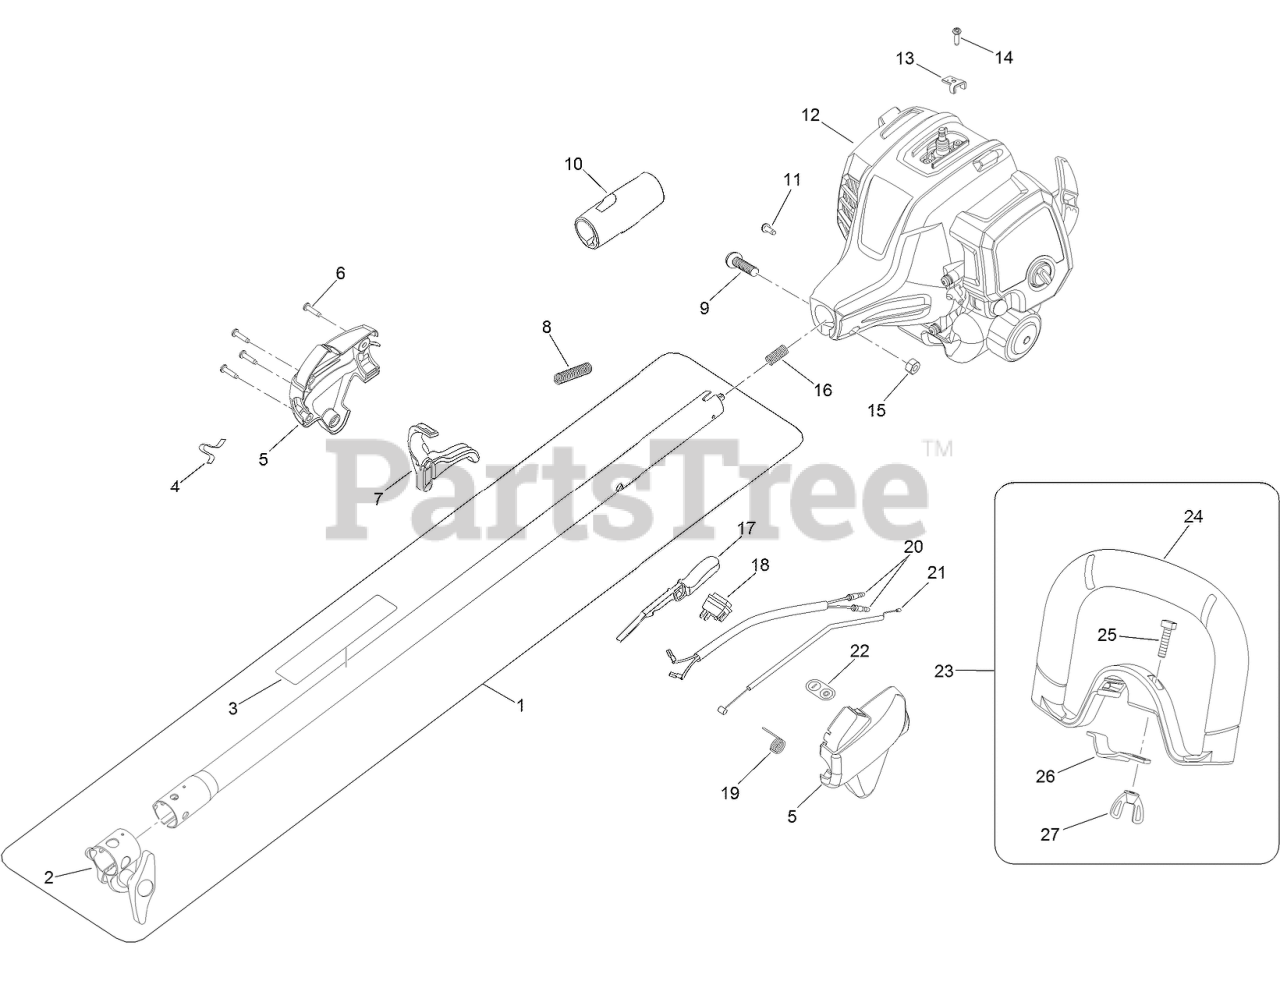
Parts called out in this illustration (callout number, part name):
1	UPPER SHAFT ASM
2	SHAFT CLAMP ASM
3	DECAL-WARNING
4	CLIP-STRAP, SHOULDER
5	CONTROL HANDLE ASM
7	TRIGGER
8	TUBE-CORRUGATED
10	GRIP-SHAFT, UPPER
12	Powerhead ASM
13	CLAMP-CABLE, THROTTLE
15	NUT-HEX
16	SPRING-COMPRESSION
17	LOCK-TRIGGER
18	SWITCH-ON/OFF
19	SPRING-TRIGGER
21	CABLE-THROTTLE
22	LABEL-ON/STOP
23	HANDLE ASM
24	HANDLE-SHAFT, UPPER
26	CLAMP-HANDLE, UPPER SHAFT
27	NUT-WING
